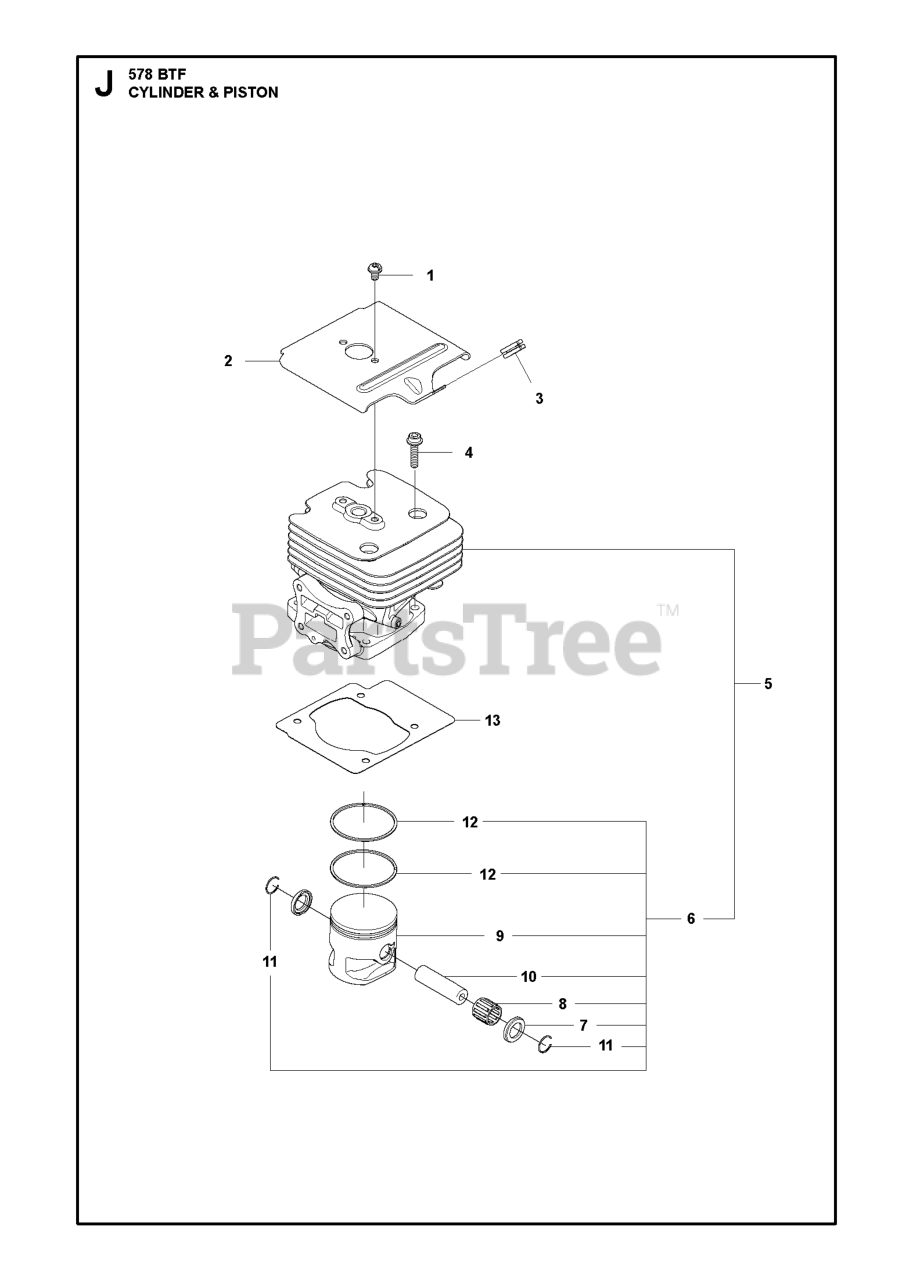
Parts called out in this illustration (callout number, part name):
5	CYLINDER ASSY
10	PISTON PIN
12	PISTON RING
